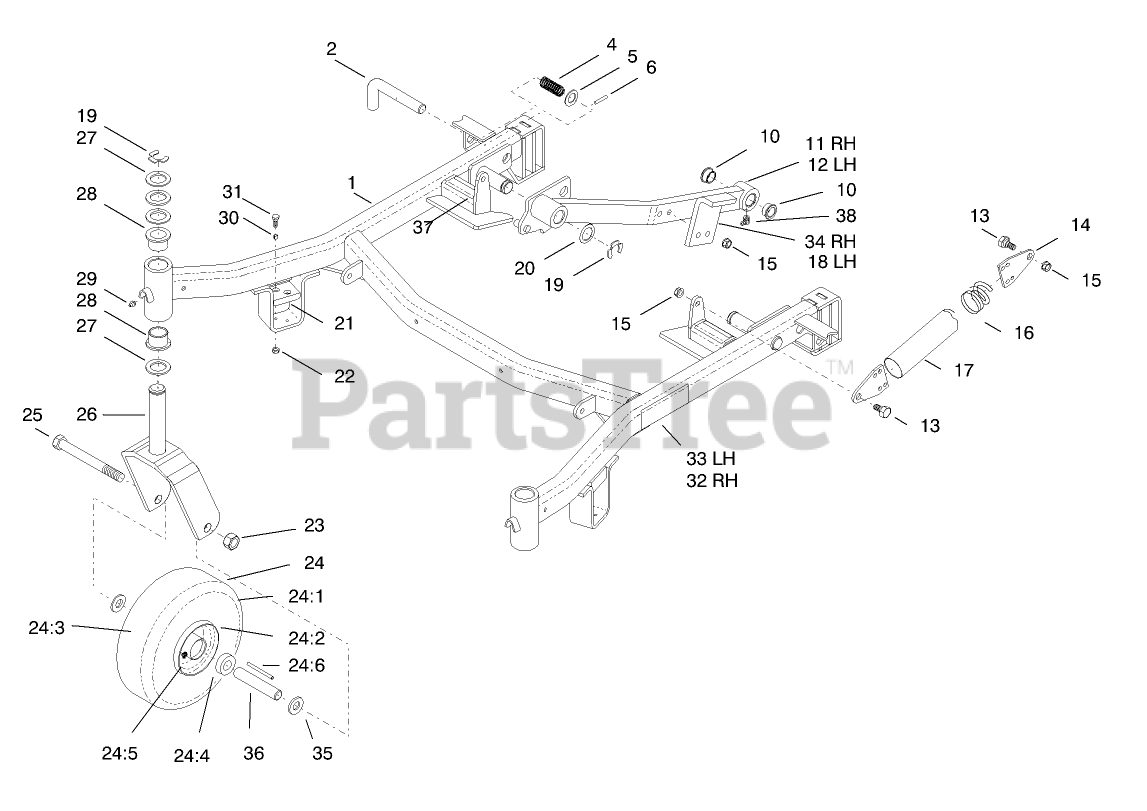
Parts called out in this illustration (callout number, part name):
1	FRAME-CARRIER
2	PIN - PIVOT
4	SPRING-COMPRESSION
5	WASHER
6	PIN-ROLL
7	SCREW-HH
10	BEARING-FLANGE
11	RH Push Arm ASM
12	LH Push Arm ASM
13	BOLT-SHOULDER
14	PLATE-END, SPRING
15	NUT-LOCK, NI
16	SPRING-EXTENSION
17	COVER-SPRING
18	Stop-Pusharm
19	RING-RETAINING
20	Washer
21	CUSHION-RUBBER
22	NUT-LOCK, NI
23	NUT-HEX
24	WHEEL/TIRE ASM
24:2	Rim/Hub ASM
24:3	TUBE- W/VALVE
24:4	BEARING-OUTSIDE
24:5	FITTING-GREASE, 90 DEG
24:6	BEARING
25	SCREW-HH
26	FORK-CASTOR
27	WASHER-THRUST
28	BUSHING
29	FITTING-GREASE
30	SPACER
31	SCREW-HH
32	DECAL-HOC, RIGHT
33	DECAL-HOC, LEFT
34	STOP - PUSH ARM,RH R
35	WASHER-FLAT
36	SPANNER
37	DECAL-WARNING
38	FITTING-GREASE
